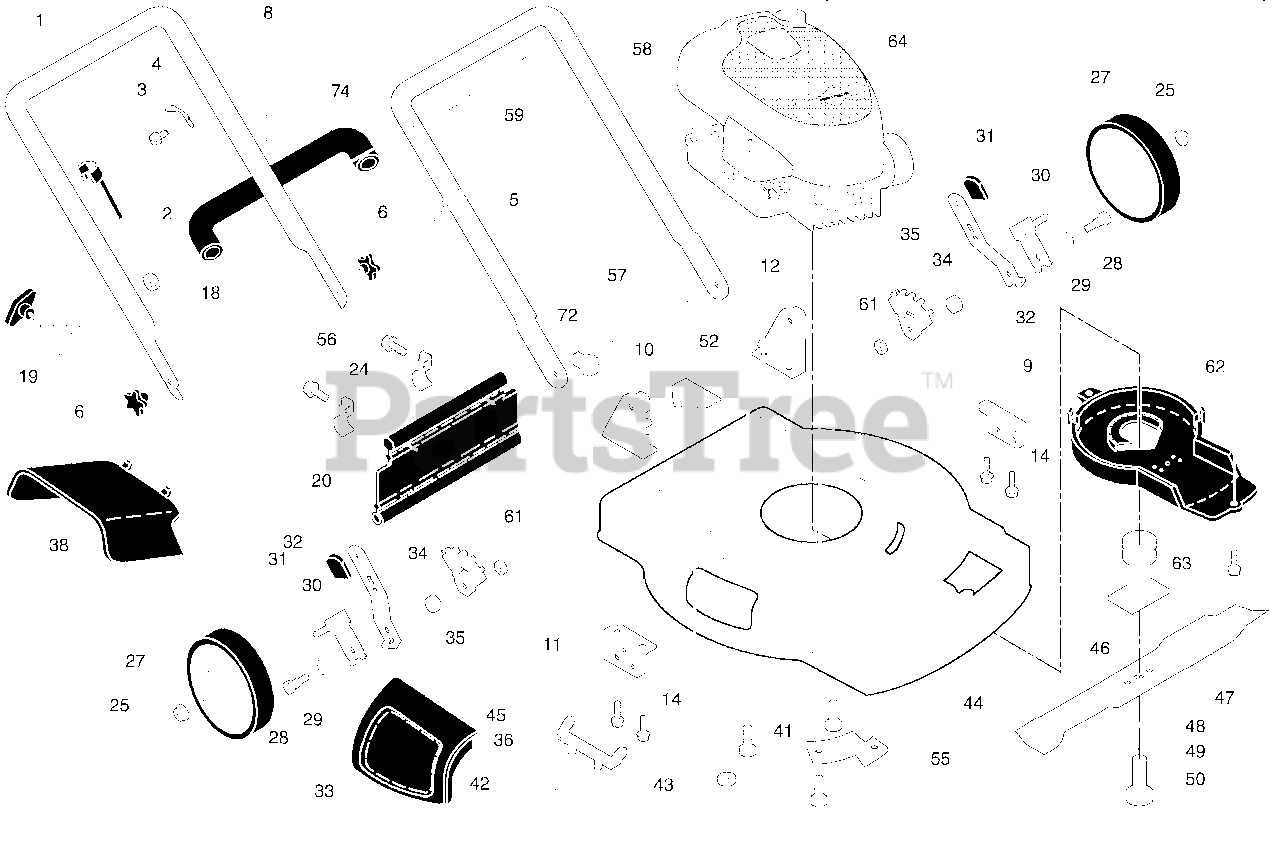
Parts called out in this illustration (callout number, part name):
1	Upper Handle Assembly
2	Engine Zone Control Cable
3	Screw
4	Bracket, Upstop
5	Wire Tie
6	Handle Knob
8	Control Bar
9	Support Bracket, Handle, LH
10	Handle Bracket, RH
11	Support Bracket, Handle, RH
12	Handle Bracket, LH
14	Screw, Thread Cutting 5/16-18 x 3/4
18	Locknut, Keps
19	Rope Guide
20	Rear Skirt
24	Clamp, Rear Skirt
25	Locknut, Hex 3/18-16
27	Wheel & Tire Assembly
28	Shoulder Bolt
29	Washer, Curved, Cylindrical
30	Axle Arm Assembly
31	Knob, Selector
32	Spring, Selector
33	Mulcher Door
34	Spacer
35	Bracket, Wheel Adjuster
36	Bracket, Housing
38	Deflector, Discharge
41	Screw, Hex Head, Threaded, Rolled 3/8-16 x 1-1/8
42	Spring, Torsion
43	Locknut, Hex
44	Kit, Lawn Mower Housing
45	Rod, Hinge
46	Blade Adapter / Pulley
47	Blade, 22"
48	Washer, Hardened
49	Washer, Lock, Helical
50	Screw, Hex Head, Grade 8 3/8-24 x 1-3/8
52	Decal, Danger
55	Mounting Bracket, Debris Shield
56	Screw, Hex Washer Head #10-24 x 1/2
57	Hairpin Cotter
58	Lower Handle
59	Handle Bolt
61	Locknut, Hex
62	Debris Shield
63	Screw
72	Clip, Cable
74	Grip, Foam
74	Operator's Manual, English
74	Operator's Manual, French
